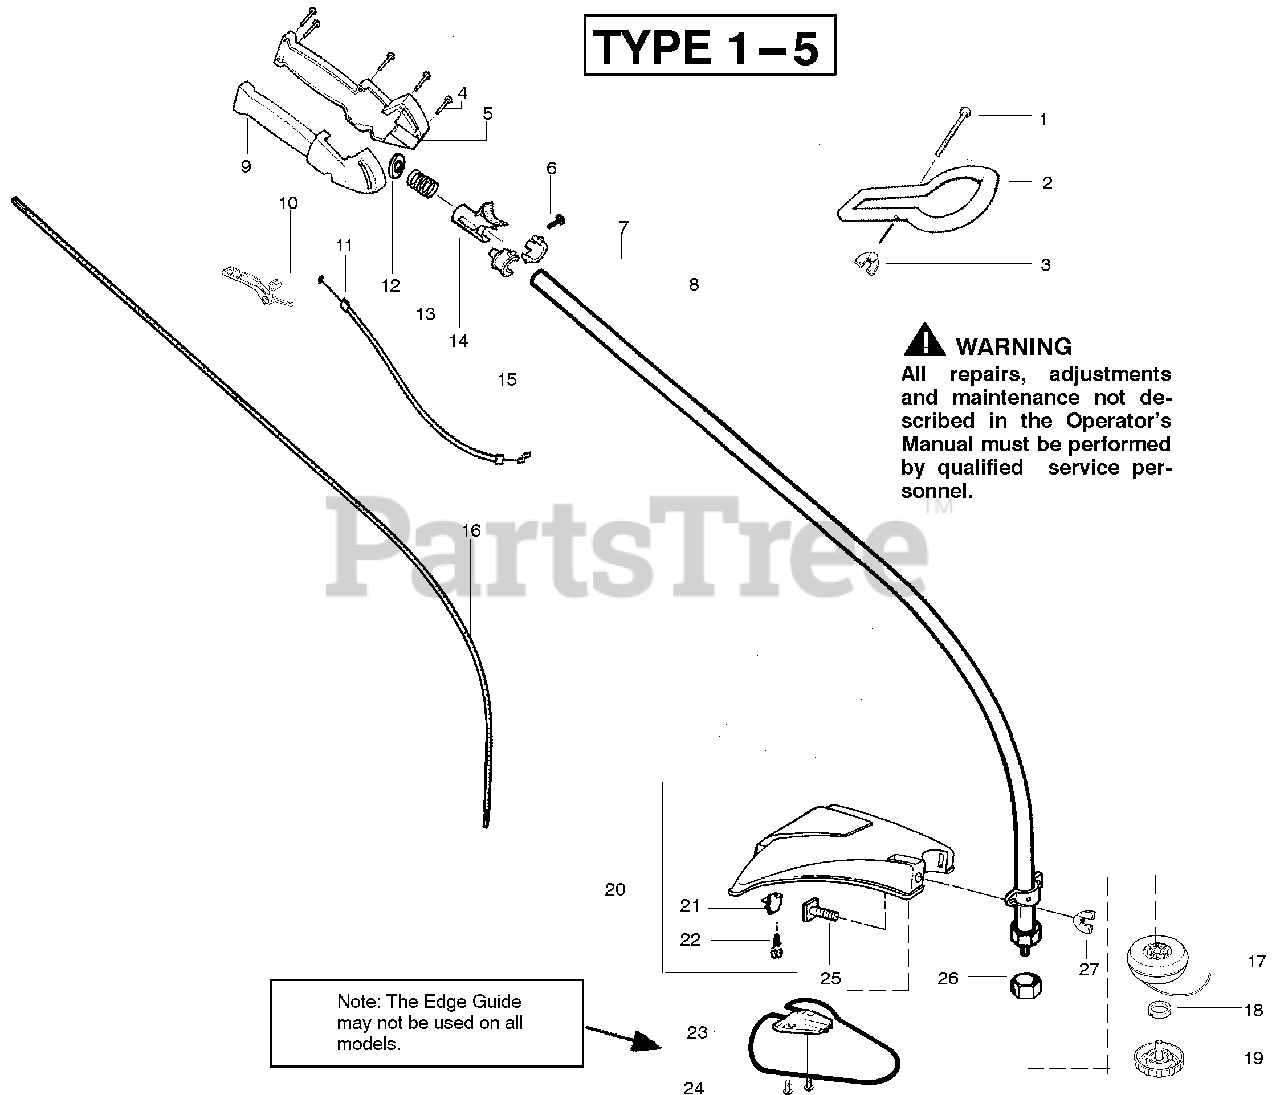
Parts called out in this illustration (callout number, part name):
1	Bolt-Handle
2	Assist Handle
3	Wingnut
5	Throttle Hsg. (Left)
6	Screw
7	Locator-Left
8	Drive Shaft Hsg. Ass'y
9	Throttle Hsg. (Right)
10	Trigger - Throttle
11	Throttle Cable Ass'y.
13	Spring-Compression
14	Actuator
15	Locator-Right
16	Drive Shaft - Flex
17	Assy. - Wound Hub
18	Guide - Line
19	Assy. - Cap 5/16"
20	Kit-Shield Ass'y.
21	Line Limiter
22	Screw-Line Limiter
23	Assy-Edge Guide
25	Bolt-Shield
26	Dust Cup
27	Wingnut
